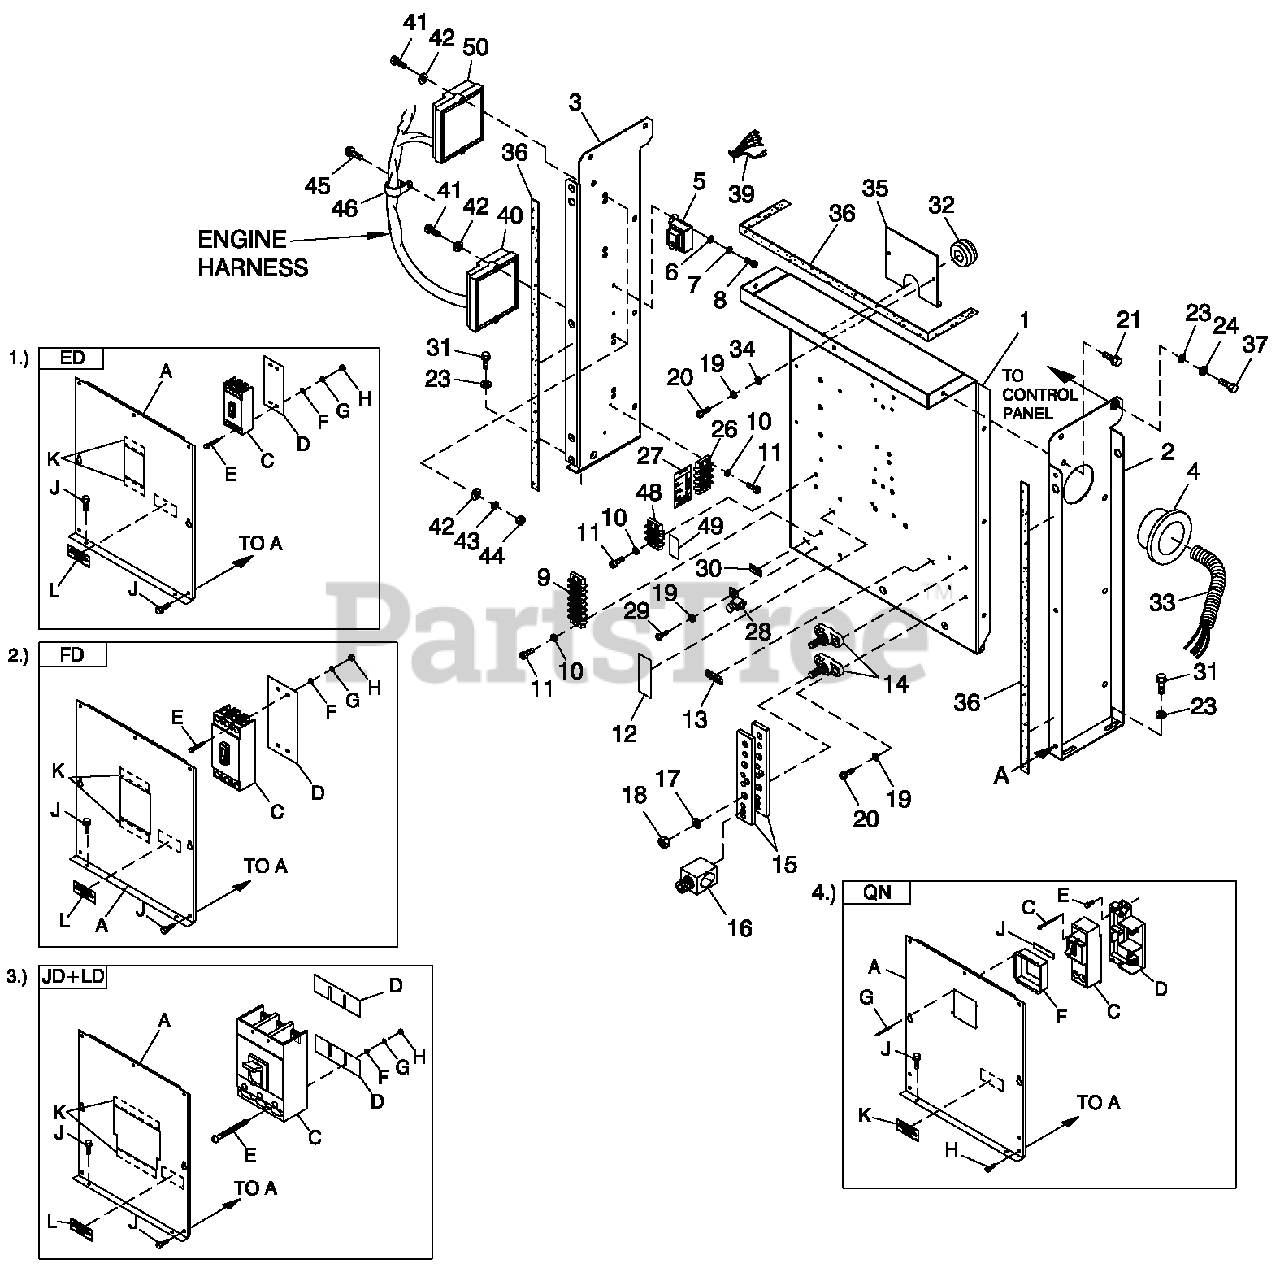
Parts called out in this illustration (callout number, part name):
1	PAN CB CONN BOX
1	UL CIRCUIT BR EAKER (ED)
2	STAND RH CONTROL
2	UL CIRCUIT BR EAKER (FD)
3	STAND LH CONTROL
3	UL CIRCUIT BR EAKER (JD+LD)
4	BUSHING SNAP SB-2.5-31
4	UL CIRCUIT BR EAKER (QN)
5	XFMR DU AL 120V/16V (FOR 120/240V & 277/480V UNITS)
6	WASHER FLAT M4
7	WASHER LOCK #8-M4
8	SCREW PHTT M 4 -0 .7 X 10 ZYC
9	BLOCK TERM 20A 6 X 6 X 1100V
10	WASH ER LOCK #6
11	SCREW PHTT # 6 -3 2 X 1 /2 ZYC
12	DECAL RTS CUSTOMER CONNECTION
13	DECAL NEUTRAL
14	JUNCTION BLO C K 3/8-16
15	BUS BAR NEUTRAL BLOCK 390
16	LUG SLDLSS 600/250-1/0 X 1/4-28
17	WASH ER LOCK 3/8
18	NUT HEX 3/8-16 STEEL
19	WASH ER LOCK M5
20	SCREW PHTT M 5 -0 .8X 16 ZYC
21	SCREW THF M6-1 X 16 N WA Z/JS
23	WASHER FLAT 1/4-M6 ZINC
24	WASHER LOCK M6-1/4
26	BLOCK TERM 20A 6 X 3 X 1100V
27	DECAL CHARG ER POWER 120VAC C2
28	LUG SLDLSS # 6 -1 4 X 13/64 CU
29	SCREW HHTT # 1 0 -3 2 X 3 /8 CZ
30	DECAL GROUND LUG
31	SCREW HHTT M 6-1.0X 16 ZYC
32	GROMMET 1.25 X .25 X .75
33	CONDUIT FLEX 2.0" ID (36" LG)
34	WASH ER FLAT M5
35	PLATE WIRE S N G LG A LV
36	TAPE ELEC 1/2 FOAM (AS REQ' D)
37	SCREW HHC M 6-1.0X 16G 8.8
39	HARNESS, TRANSFORM ERADAPTER
40	PCB ENCLOSURE ASSY 4.2L IGN MD
41	SCREW PPHM # 10 /3 2 X 2
42	WASH ER FLAT #10 ZINC
43	WASH ER LOCK #10
44	NUT HEX #10-32 STEEL
45	SCREW THF M6-1 X 16 N W A Z/JS
46	CLAMP V IN YL 1.06 X . 406 Z
47	SEAL W EATH ER .45"D IA
48	BLO C K TERM 20A 2 X 6 X 1100V
49	DECAL GTS CUSTOMER CONNECTION
50	ASSY PCB IGN MOD 2.4L NO-TURBO
A	COVER ED CB SHORT STND
C	CB 0050A 3P 480V S ED4 LL
D	INSULATOR CB S (ED -3P)
E	SCREW RHM # 10 -3 2 X 4 -1 /2
F	WASH ER FLAT #10 ZINC
G	WASH ER LOCK #10
H	NUT HEX #10-32 STEEL
J	SCREW THF M6-1 X 16 N W A Z/JS
K	TAPE ELEC 1/2 FOAM (AS REQ' D)
L	DECAL CUSTOMER CONNECT INSIDE
A	COVER C B CONN BOX
C	CB 0150A 3P 600V S FD6 LL
D	INSULATO R CB FD FRAME 30M IL
E	SCREW SHC 1/4-20 X 4.5 G8.8 NZ
F	W ASH ER FLAT 1/4-M6 ZINC
G	W ASH ER LOCK M6-1/4
H	NUT HEX 1/4-20 STEEL
A	COVER JD /LD C B SHRT STAND
C	CB 0300A 3P 600 V S J D 6 LL
D	INSULATO R CIRCUIT BR. JD/LD
E	SCREW RHM 1 /4 -2 0 X 3
F	WASH ER FLAT 1/4-M6 ZINC
G	WASH ER LOCK M6-1/4
A	COVER Q N F R M C B
C	CB 0150A 2P 240V S QN2 LL
D	BASE, QN CIRCUIT BR EAKER
E	SCREW HHTT M 5-0.8X 10 BP
F	COVER Q N C B DISH
G	RIVET POP .1 2 5 X . 2 7 5 SS
H	SCREW THF M6-1X16 N W A Z /J S
J	TAPE ELEC 1/2 FOAM (AS REQ' D)
K	DECAL CUSTOMER CONNECT INSIDE
